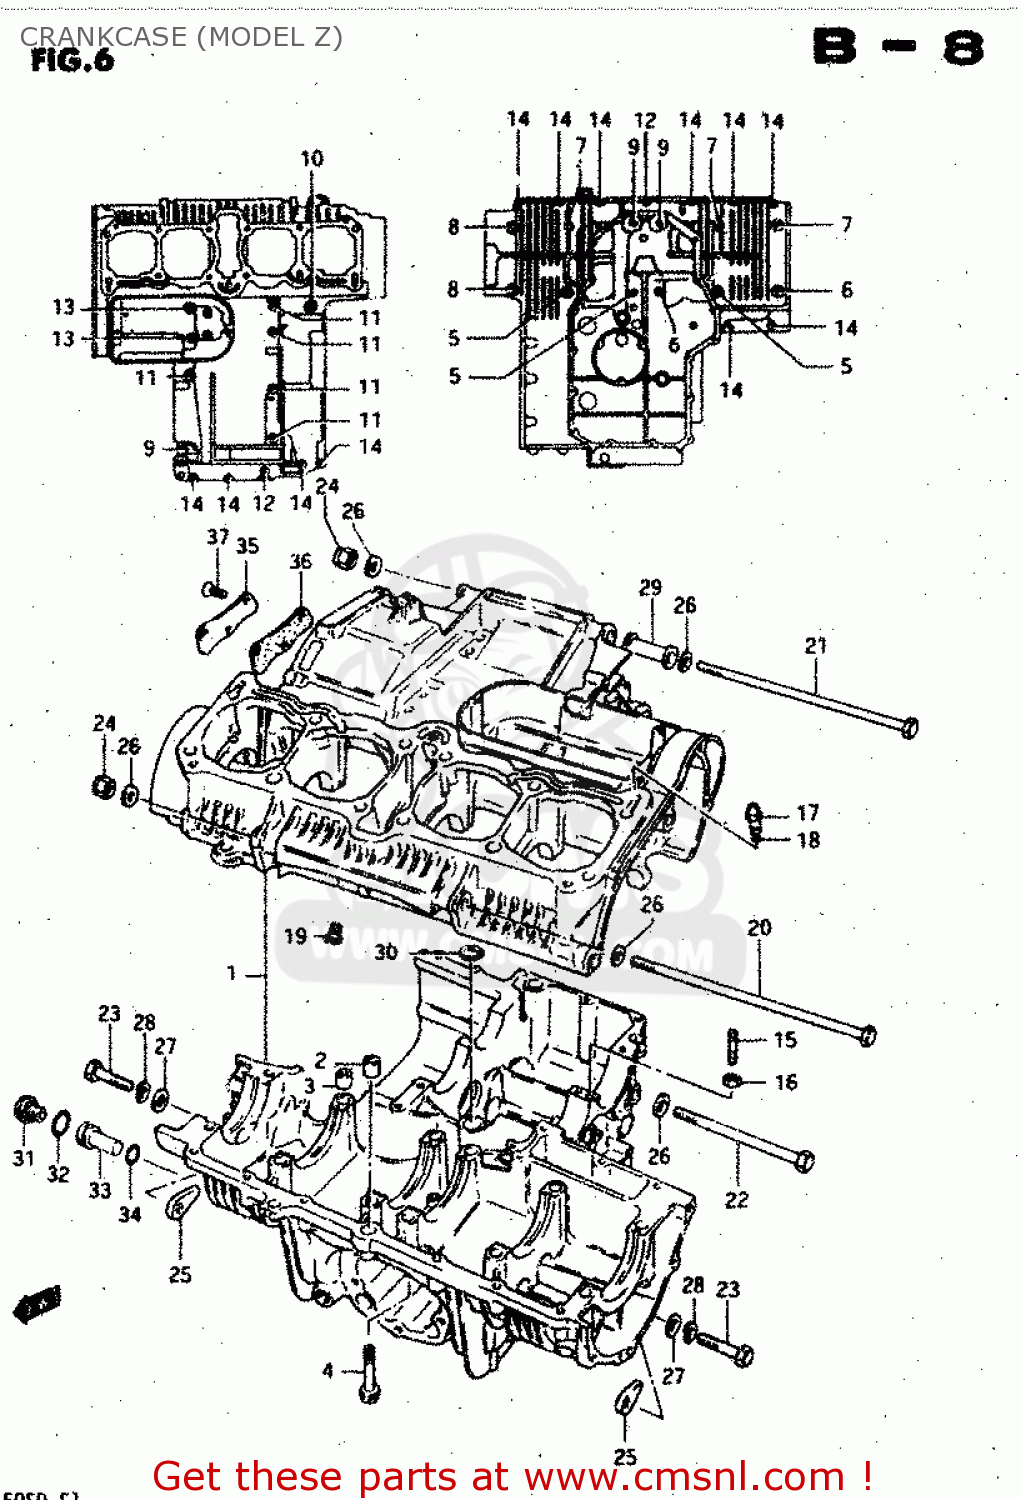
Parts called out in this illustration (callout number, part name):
1	CRANKCASE ASSEMBLY
2	PIN(10.4X13X22)
3	PIN (11X20)(SUS)
4	BOLT
5	BOLT(8X140)
6	BOLT
7	BOLT (8X95)
8	BOLT (8X70)
9	BOLT 8X65
10	BOLT 6X95
11	BOLT (6X80)
12	BOLT (6X60)
13	BOLT,UNDER
14	BOLT
15	STUD BOLT
16	NUT
17	JET
18	O RING(D:1.05,ID:3.1)
19	JET,AIR
20	BOLT(10X225)
21	BOLT(10X250)
22	BOLT(10X165)
23	BOLT 10X60
24	NUT
25	NUT
26	WASHER
27	WASHER(10.5X20X3.2)
28	LOCK WASHER
29	SPACER
30	O RING(D:3.2,ID:12.9)
31	PLUG
32	O RING(D:2.4,ID:17.8)
33	PIN,OIL GALLERY
34	SEAL (D:1.9 ID:9.8)
35	CAP,OIL GALLERY
36	GASKET
37	SCREW
